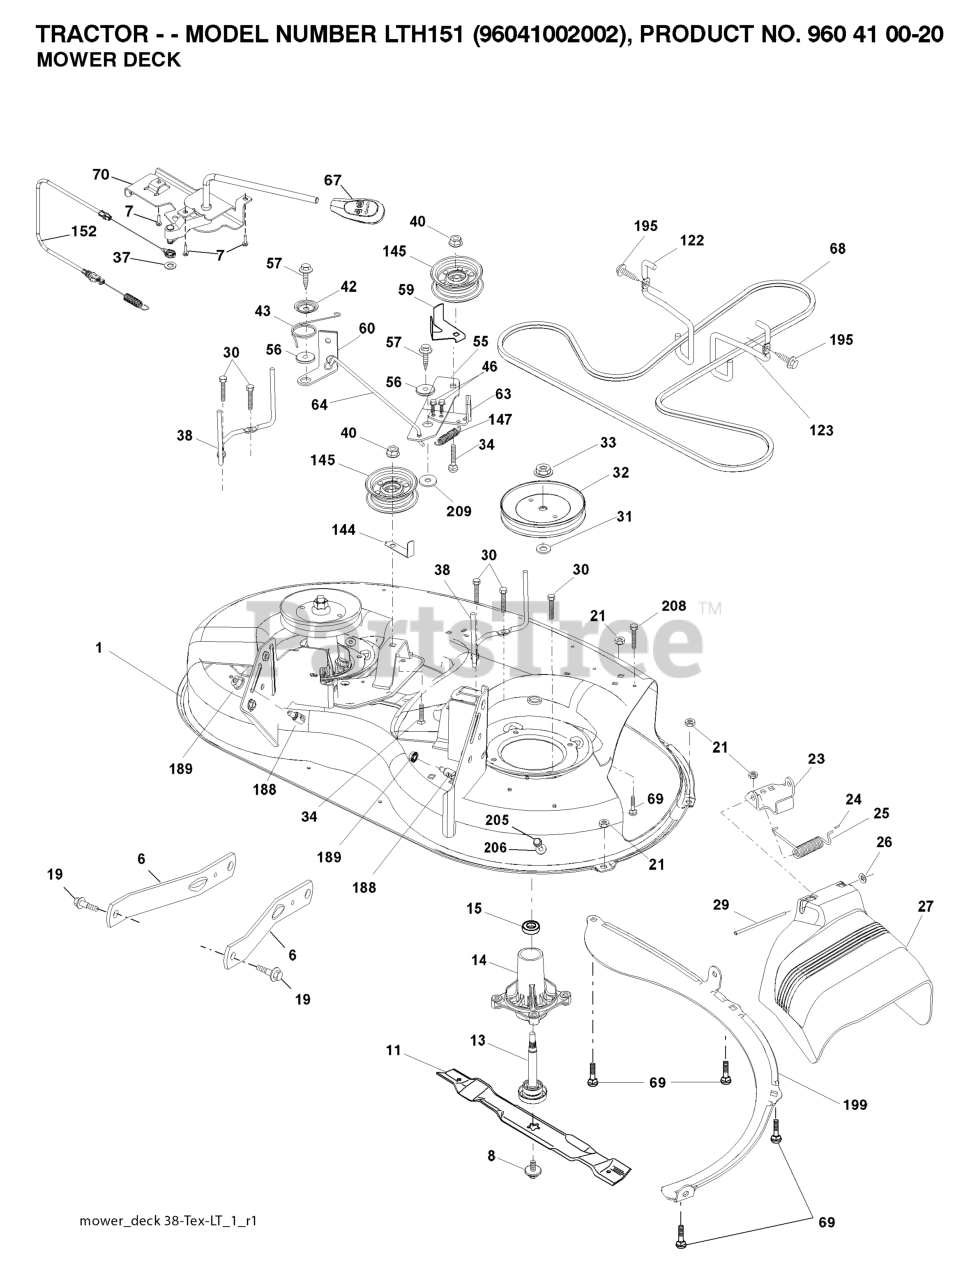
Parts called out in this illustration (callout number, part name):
1	HOUSING
6	ARM.SUSPENSION.MOWER.R
7	SCREW
8	BOLT.WASHER.ASM.7/16-2
11	BLADE 38" PREMIUM
13	SHAFT.ASM.MDRL.N/GREASE.38
14	RP.HOUSING.MANDREL.4PT.
19	BOLT.SHOULDER
21	LOCKNUT
23	BRKT.DEFLECTOR.38"2005+
24	CAP-SLEEVE LT
25	SPRING.TORSION.DEFLECT
26	NUT PUSH M
27	SHIELD ASM.DFLCTR MWR.38-7"BLK
29	ROD.HINGE
30	SCREW, WASHER HEAD
31	WASHER.SPACER.MANDREL
32	PULLEY.MANDREL.5.0.PD.38"
33	NUT.FLANGE.LOCK.TOP
34	BOLT.3/8-16X1.50
37	WASHER
38	KEEPER BELT LH MANDREL
40	NUT LOCK FLG 3/8-16 UNC
42	SPRING.TORSION.BRAKE
43	SRPING.TORSION.RETAINE
46	SCREW.1/4-20X5/8
56	SPACER.RETAINER
57	SCREW 3/8-16X1
59	GUARD, BELT
60	ARM BRAKE MOWER RH 38"
63	RP ARM.BRAKE.MOWER.38"LH.TEX
64	LINK BRAKE
67	HANDLE.CLUTCH.CABLE.LT
69	BOLT
70	CLUTCH.ASM.MANUAL.LT.PRED
122	KEEPER BELT ENGINE LH
123	KEEPER BELT RH
144	KEEPER BELT
145	PULLEY.IDLER.48"PRIMARY
147	SPRING RETURN
152	CLUTCH CABLE
188	STUD.FASTNER.W/ANTI-ROTATE
189	NUT LOCK HEX FLANGE 5/16-18
195	SCREW, 3/8-16X3/4
199	BAFFLE.VORTEX.FRONT.38"
205	SCREW
208	SCREW 3/8-16X1/2
209	WASHER 12/32X2X10GA
